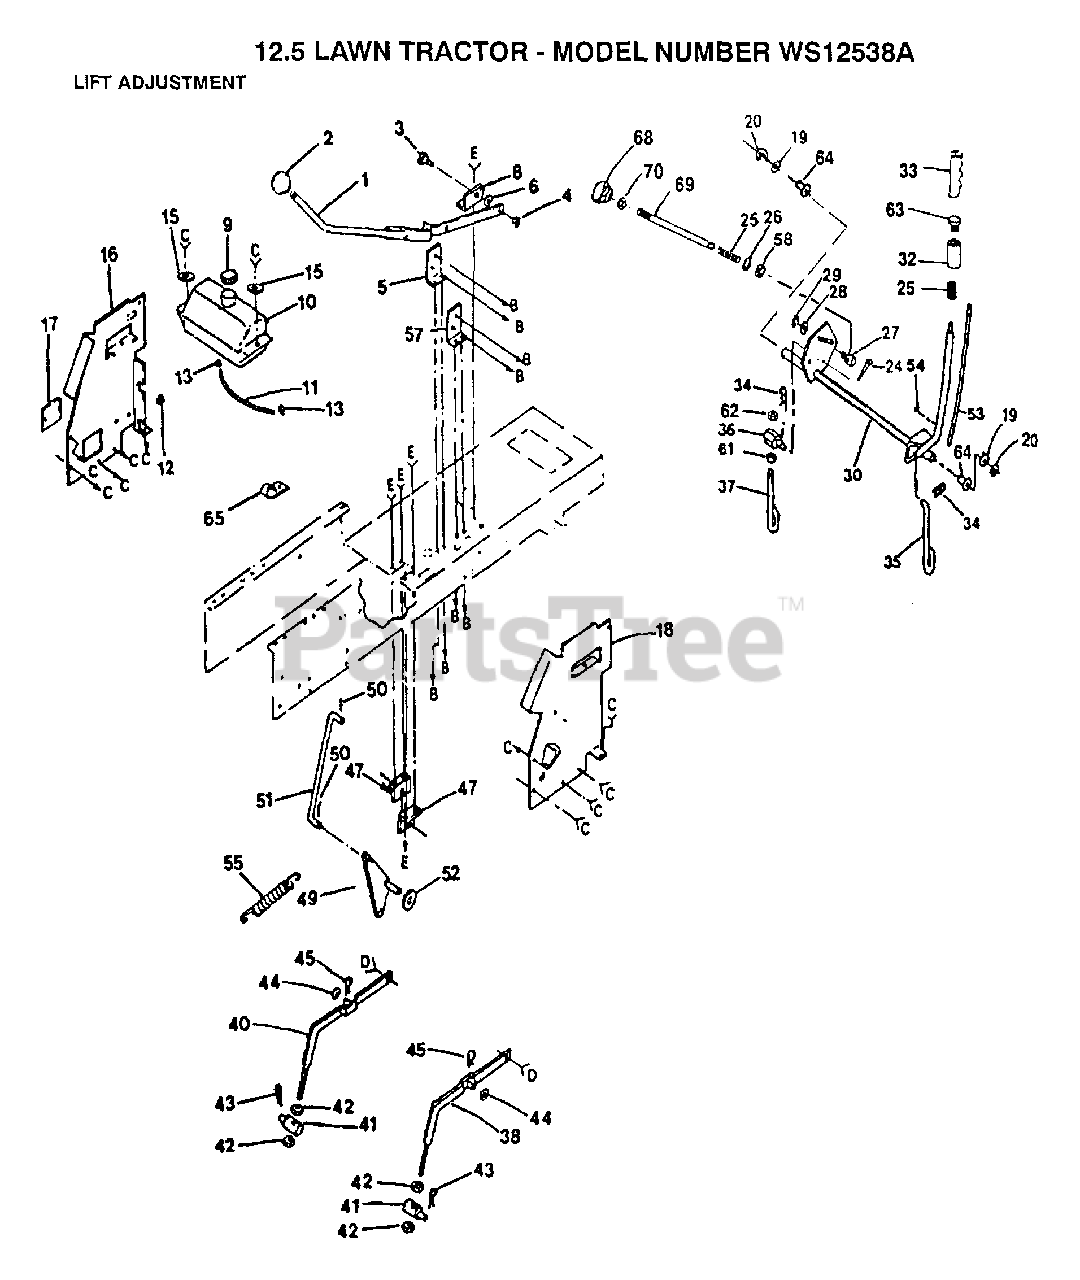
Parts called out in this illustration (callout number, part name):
3	"BOLT, SHOULDER LT"
5	"BRACKET,SWITCH LT"
8	"SUP,LVR,CLUTCH LT"
10	TANK.FUEL.LT.
13	HOSE CLAMP
15	WASHER
16	PANEL DASH LH
17	COVER ACCESS
19	WASHER
26	WASHER
27	TRUNION LT
28	WASHER
29	KLIP RING
33	GRIP
35	LIFT LINK LT
37	PIVOT PIN T
38	RH SUSP ARM ASM
40	LH SUSP ARM ASM
42	NUT
43	SPRING H
45	SPRING.RETAINER
47	"BRKT,BELLCRAN T"
49	"T, BELLCRANK"
50	COTTER PIN
52	WASHER
54	PIN-GROOVE LT
57	BRACKET LT
58	NUT T
61	NUT
64	NYLON BEARING
65	INSUL CLIP T
68	HDLE ADJ LIFT
70	NUT
